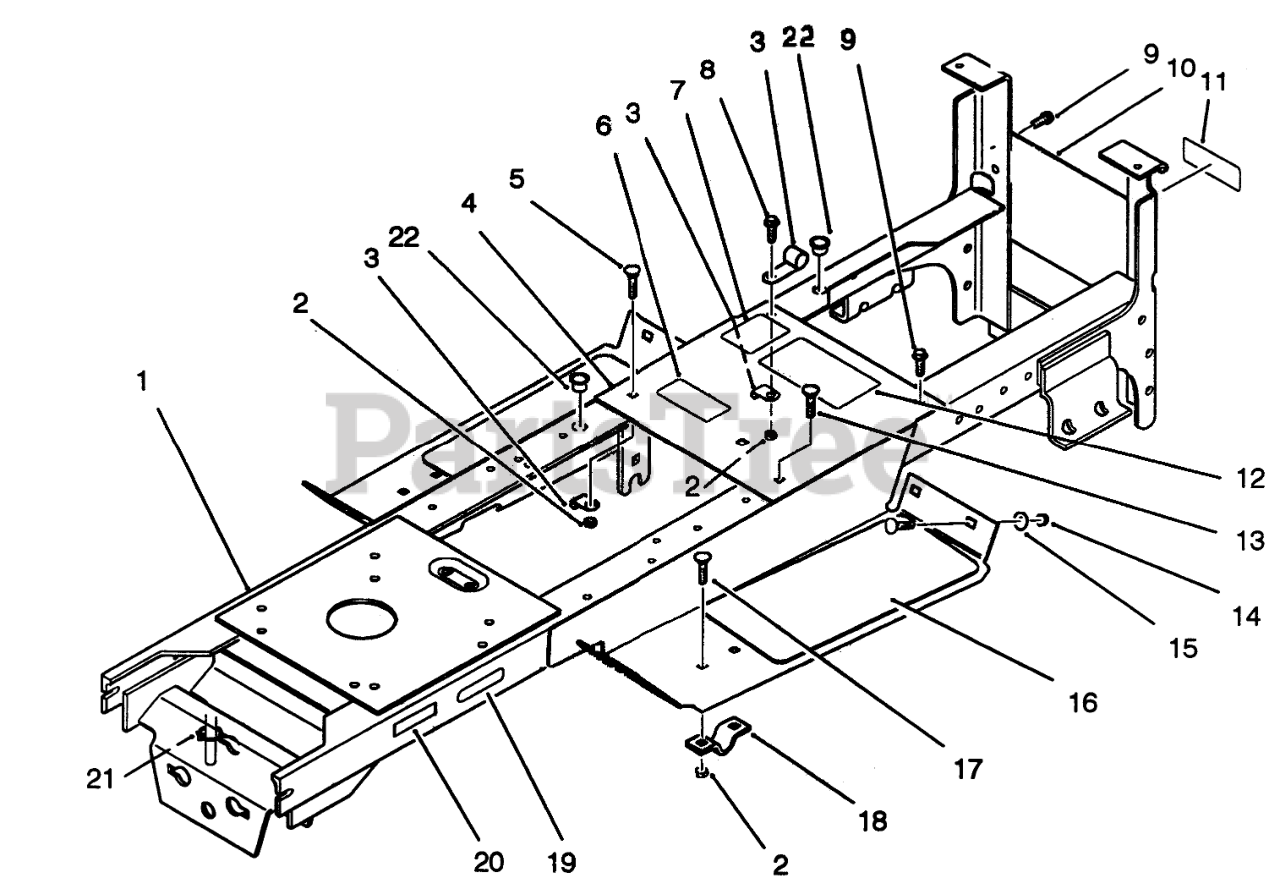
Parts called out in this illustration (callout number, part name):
1	Frame
2	NUT-LOCK, NI
3	THROTTLE CONTROL CLP
4	Panel
5	Bolt-Carriage
6	DECAL-DANGER
7	DECAL-PARKING BRAKE
8	Bolt
9	Screw
10	PANEL-REAR R
11	DECAL-DANGER
12	DECAL-DANGER
13	SCREW-CARR
14	NUT-HEX
15	WASHER - FLAT YZ
16	PAD FOOTREST
17	NUT-HEX, JAM
18	CLAMP
19	DECAL-INSTALL BELT
20	Decal-Attac-O-Matic
21	PLASTIC TIE
22	BUSHING
